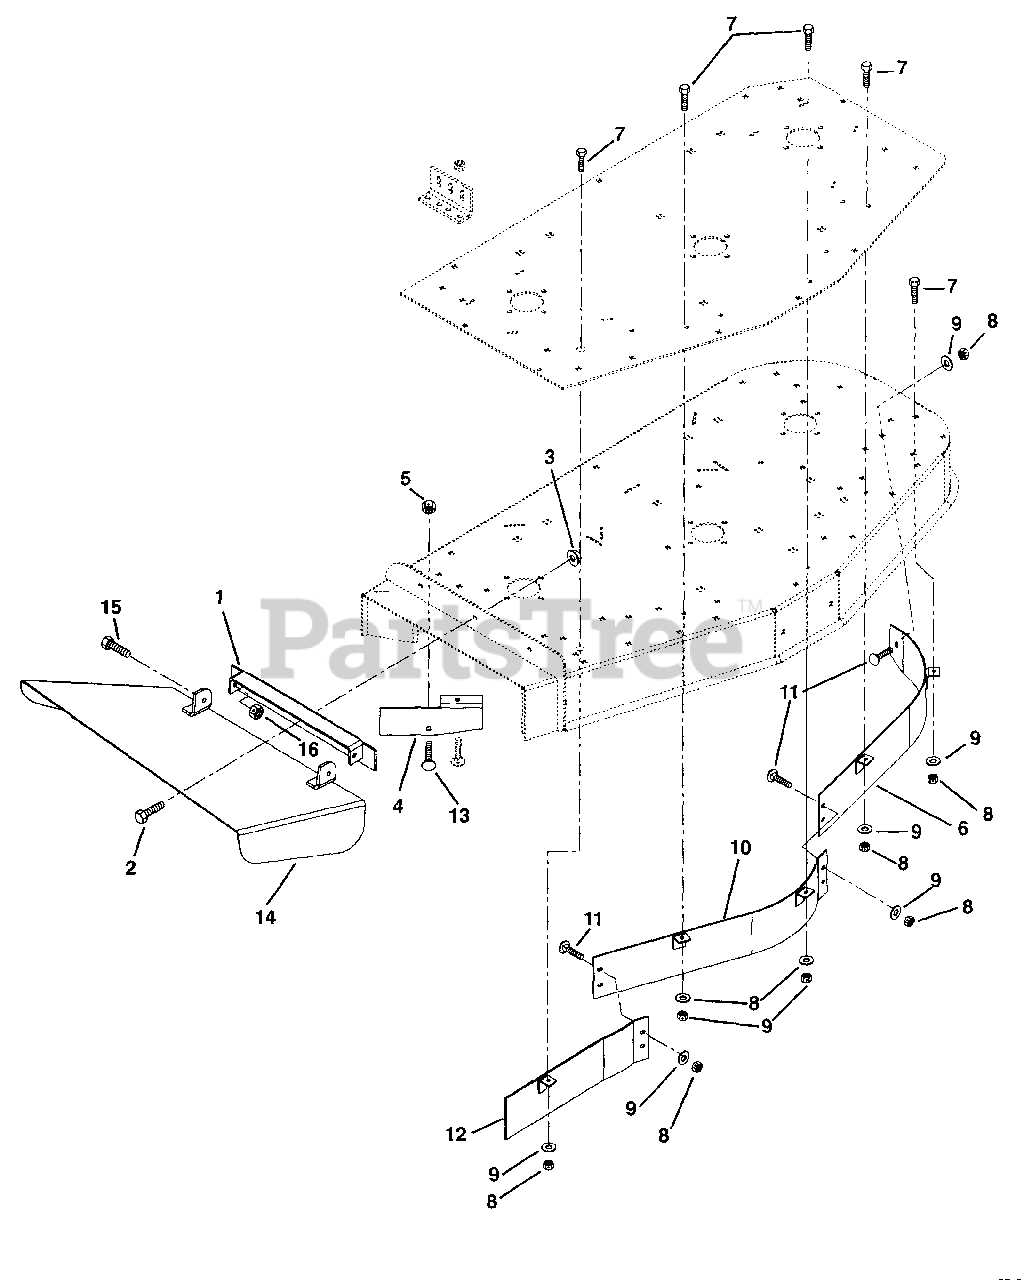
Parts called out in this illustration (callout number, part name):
1	Weldment, Discharge Chute Bracket
2	Bolt-Hex .38-16 x 1.00 Grade 5
3	Nut-Locking-Flange .38-16
4	Deflector
5	Nut-Locking-Center .38-16
6	Weldment, 50" Left Hand Baffle-Upper
7	Bolt-Hex .31-18 x 1.00 Grade 5
8	Nut-Locking-Nylon .31-18
9	Washer-Flat-Steel .312 x .734 x .065
10	Weldment, 50" Center Baffle-Up
11	Bolt-Round Head Square Neck .31-18 x .75 Grade 5
12	Weldment, 50" Right Hand Baffle-Upper
13	Bolt-Round Head Square Neck .38-16 x 1.00 Grade 2
14	Weldment, Discharge Chute 50"
15	Bolt-Hex .38-16 x 1.00 Grade 5
16	Nut-Locking-Center .38-16
17	50" Mulch Kit
18	50" Discharge Cover
